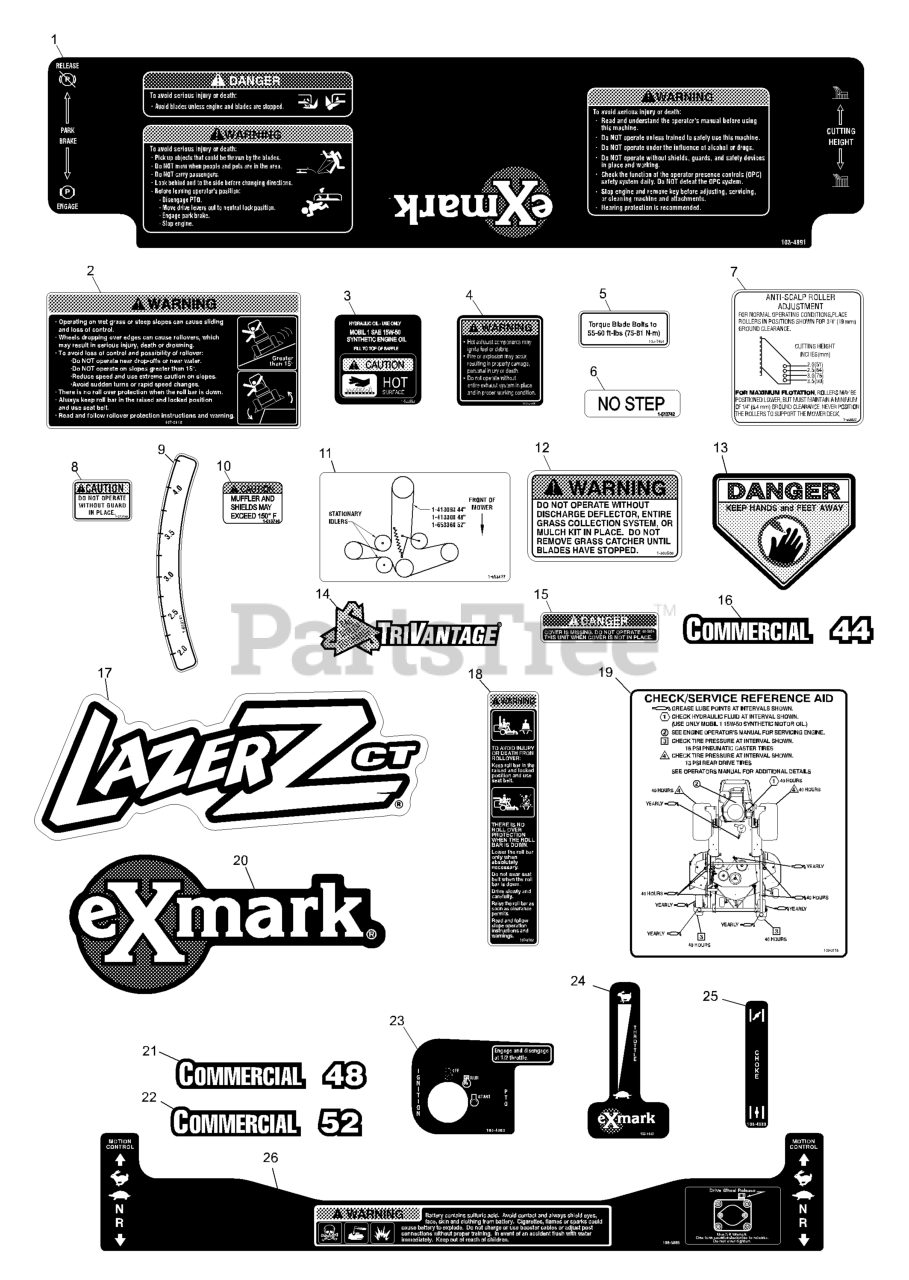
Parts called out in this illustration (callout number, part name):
1	DECAL,CONSOLE LHP
2	DECAL-WARNING
4	DECAL-EXHAUST
6	DECAL,NO STEP
7	DECAL,ANTISCALP
8	DECAL-GUARD
9	DECAL-DECK HEIGHT, INNER
12	DECAL-WARNING, DISCHARGE
13	DECAL-DANGER
15	DECAL-COVER, MISSING
16	DECAL,COMMERCIAL 44
17	DECAL,LCT MODEL
18	DECAL-WARNING, FOLDING RO
19	DECAL, CHECK/SERVICE LCT
20	DECAL,EXMARK LOGO
21	DECAL,COMMERCIAL 48
22	DECAL,COMMERCIAL 52
23	DECAL,IGNITION/PTO
24	DECAL,THROTTLE
25	DECAL,CHOKE
26	DECAL-WARNING
